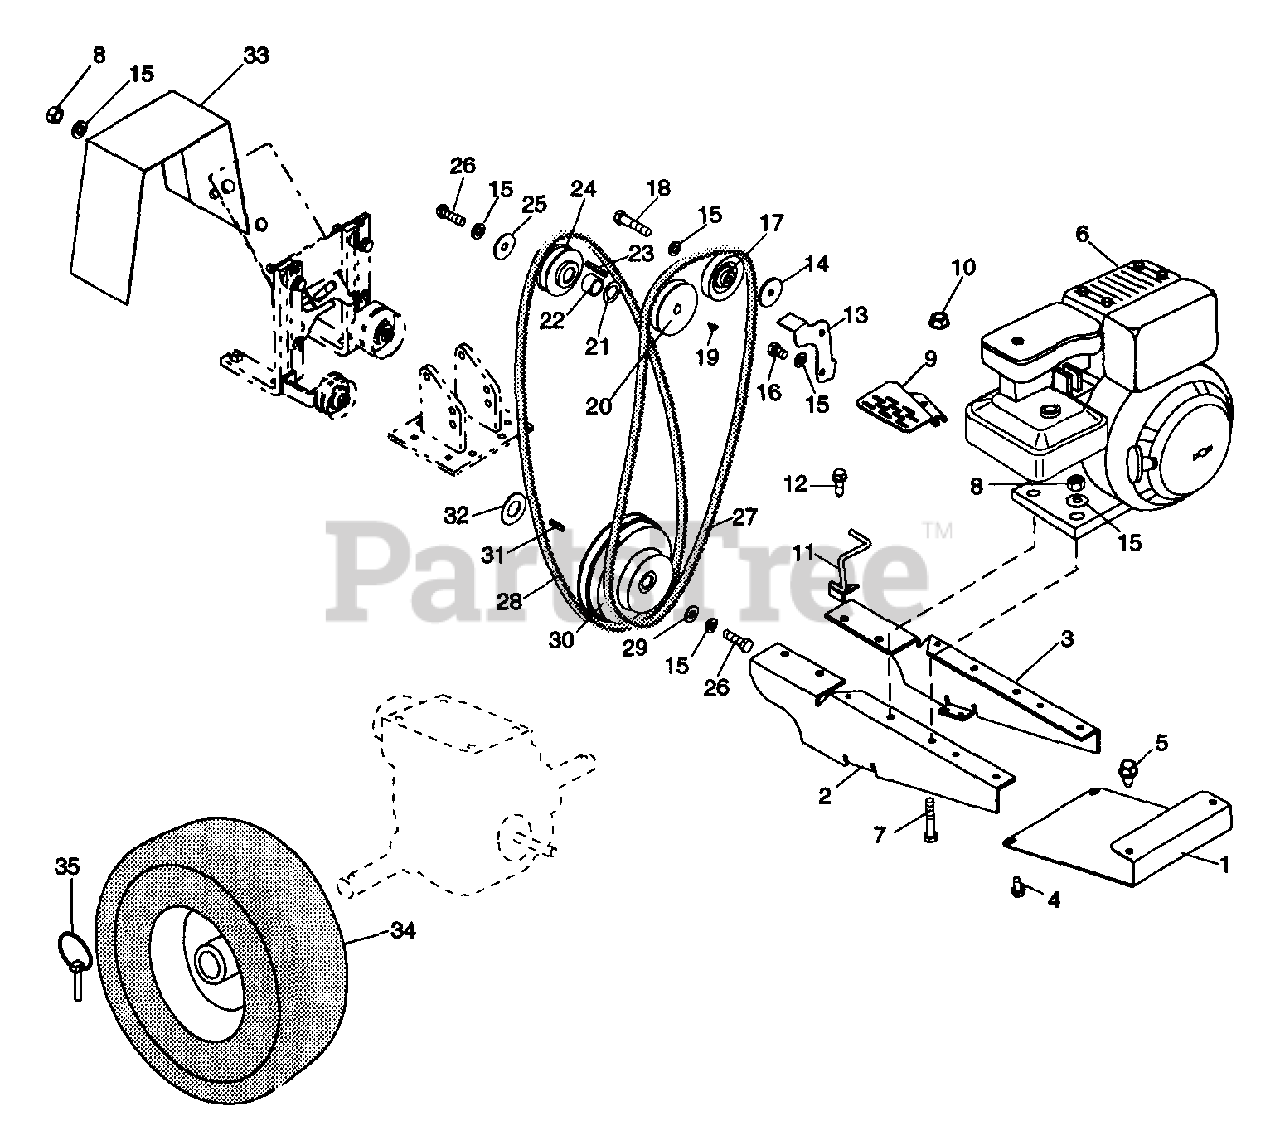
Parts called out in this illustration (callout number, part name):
1	COVER, ENGINE BRACKET
2	RH ENGINE MOUNTING BRACKET
3	LH ENGINE MOUNTING BRACKET
4	SCR-TAP .250-20X.50 HXSLHDPL
5	SCR-TAP .312-18X.50 HWH PL TR
6	5 HP BRIGGS ENG 135292-0180-01
7	BLT-HEX .31-18X1.75 GR5
8	NUT-HEX .312-18
9	MUFFLER SHIELD
10	NUT-FLG. .312-18 PL
11	BELT FINGER WELDMENT
12	SCR-TAP .250-20X.75 HWH PL TR
13	BELT FINGER
14	WSHR-FL-STL .312X1.62X.13
15	WSHR-LK .312X.097 PL HVY
16	BLT-HEX .31-24X.50 GR5
17	IDLER-V 2.625X.312
18	BLT-HEX .31-24X1.50 PL GR5
19	KEY-WDRF .125X.625X.250 SAE5
20	SHEAVE REVERSE
21	WSHR-HDND-THRST .758X1.23X.031
22	SPACER .765X.875X.750
23	KEY-SQ .188X1.5X.187 SAE 8630
24	SHEAVE, FORWARD
25	WSHR-FL-STL .344X1.125X.063PL
26	BLT-HEX .31-24X1.00 PL GR5
27	V-BELT, 3L-WRAPPED
28	V-BELT, 4L-WRAPPED
29	WSHR-FL-STL .380X.875X.179 PL
30	SHEAVE - TRANSMISSION
31	KEY-SQ .188X1.0X.188 SAE 8630
32	WSHR-FL-STL .699X1.375X.059
33	BELT GUARD
34	T/WHL ASSY RH
34	T/WHL ASSY LH
34	RIM-ASSY 1.75X3.13 SEE L-2080
35	PIN-LOK .31X2.00
